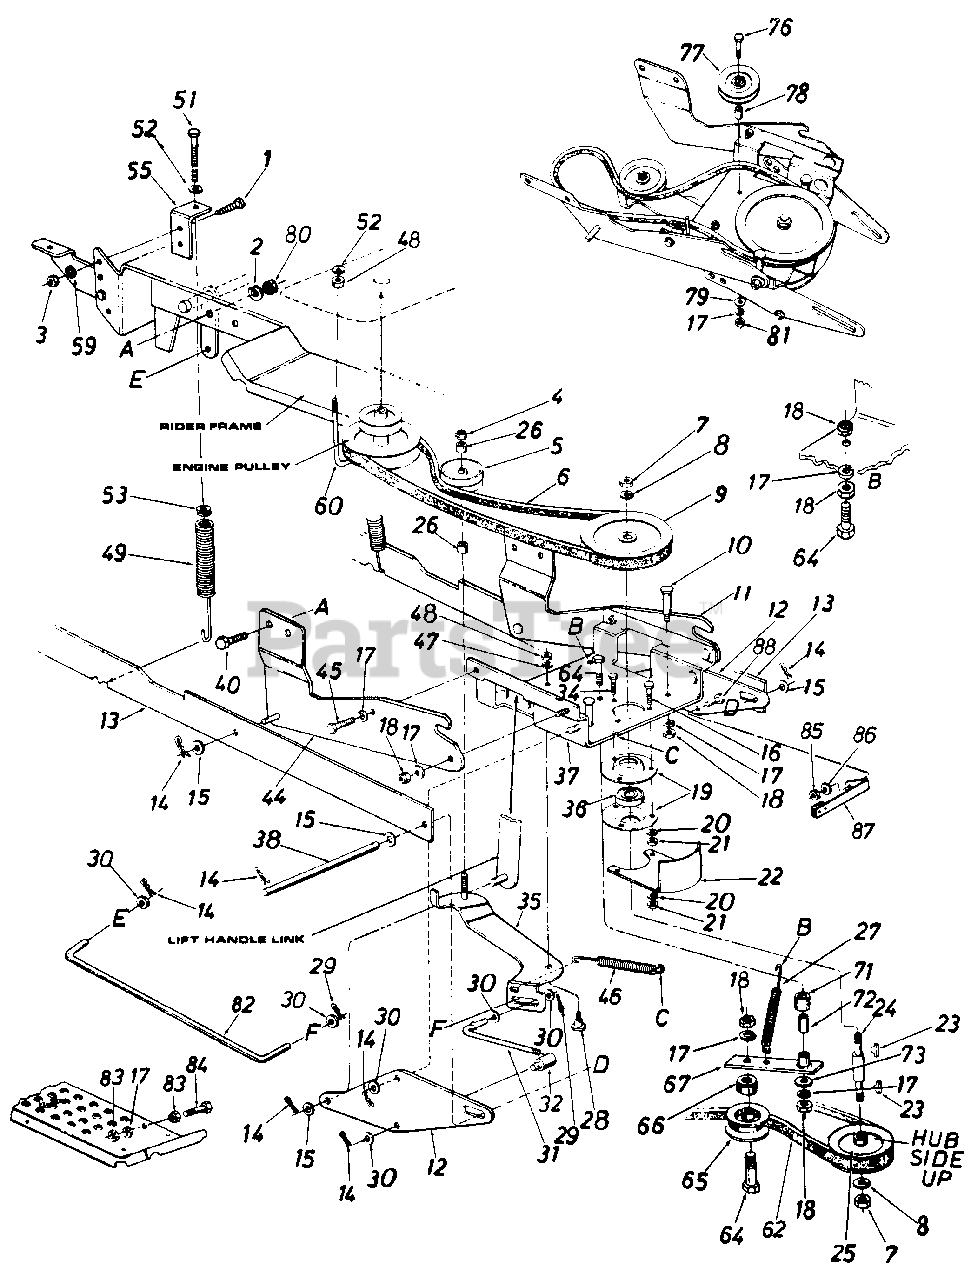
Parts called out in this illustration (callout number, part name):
1	Hex Bolt 1/4-28 x 1.0" Lg.* Gr. 5
2	1 L-Wash. 1/4" I.D.
3	Hex Nut 1/4-28 Thd.
4	1 Hex Cent. L-Nut 3/8-16 Thd.
5	Idler Pulley
6	"V"-Belt
7	Hex Jam Nut 5/8-11 Thd.
8	L-Wash. 5/8" I.D.
9	5/8 Pulley x 6.5" O.D.
10	Shoulder Bolt
11	Channel Support Brkt. R.H.
12	Linkage Brkt.
13	Linkage Arm Ass'y.
14	1 Intern. Cotter Pin .50" Dia.
15	Fl-Wash.
16	Hex Bolt 5/16-18 x 1.25" Lg.
17	L-Wash. 3/8" I.D.
18	Hex Jam Nut 3/8-16 Thd.
19	Bearing Housing
20	L-Wash. 5/16" I.D.
21	Hex Nut 5/16-18 Thd.
24	Pulley Spindle
25	5/8 Pulley 6.28" I.D. x 5.56" O.D.
26	Spacer .383" I.D. x .503" O.D. x.562" Lg.
27	Extension Spring .54" O.D. x 5.25"
28	Shoulder Bolt
29	Cotter Pin 3/32" Dia.
30	Fl-Wash.
31	Control Rod
32	Ferrule
34	Hex Sems Bolt 5/16-18 x .75" Lg.*
35	Clutch Idler Brkt. Ass'y.
36	Ball Bearing
37	Channel Ass'y.
38	LIft Handle Shaft
40	Hex Self-Tap Scr. 1/4-20 x .75" Lg.
44	Channel Supporting Brkt.-L.H.
45	Hex Bolt 3/8-16 x 1" Lg.*
46	Extension Spring
47	L-Wash. 5/16" I.D.
48	Hex Nut 5/16-18 Thd.
49	Helper Spring
51	Hex Bolt 5/16-18 x 2.0" Lg. Special
52	Bell-Wash. .345" I.D. x .88" O.D. x .06"
53	Spring Insert
60	J-Bolt 5/16-18 Thd.
62	"V"-Belt
64	Hex Bolt 3/8-16 x 2" Lg.
65	Idler Pulley
66	Spacer.385" I.D. x .503" O.D. x.562" Lg.
67	Idler Arm Ass'y.
71	Spacer.38" I.D.
72	Spacer .3775" I.D. x .6" O.D. x 8.3" Lg.
73	Fl-Wash. 3/8" I.D. x 1" O.D. x 1.27"
76	Hex Bolt 3/8-16 x 2.5" Lg. (Grade S)
77	Idler Pulley .38" I.D. x 3.06" O.D.
78	Spacer .385" I.D. x .63" O.D. x.76" Lg.
79	Fl-Wash. .39" I.D. x 1-3/4" O.D. x 3/16"
80	Hex L-Nut 1/4-20 Thd.
81	Hex Nut 3/8-16 Thd.
82	Clutch Control Rod
83	Hex Nut 3/8-24 Thd.*
84	Hex Bolt 3/8-24 x 2.25" Lg.*
85	Hex Nut 3/8-16 Thd.
86	Bell-Wash. 3/8" I.D.
87	Auger Brake Brkt. Ass'y.
88	Hex Bolt 3/8-16 x 5/8" Lg.
